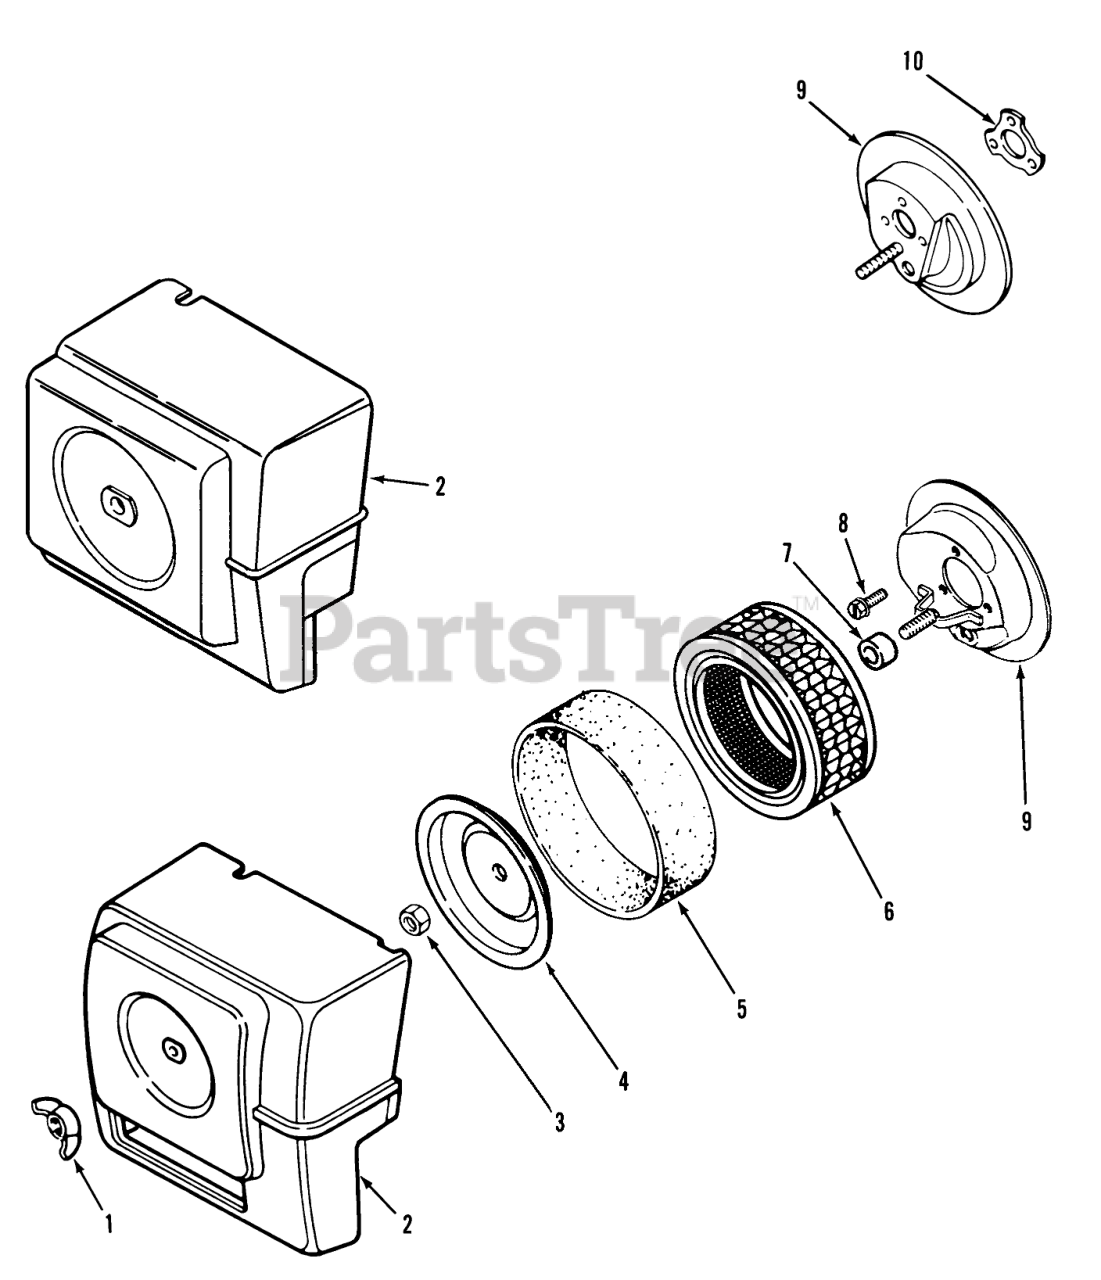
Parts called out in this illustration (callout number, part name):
1	Nut-Wing
2	Air Cleaner Cover 308 Only
4	Air Cleaner Element Cover
5	Precleaner Element 308 Only
6	Element 308 Only
7	Seal 308 Only
8	Screw-Hex. Hd.
9	Air Cleaner Base 308 Only
10	Air Horn Gasket 308 Only
